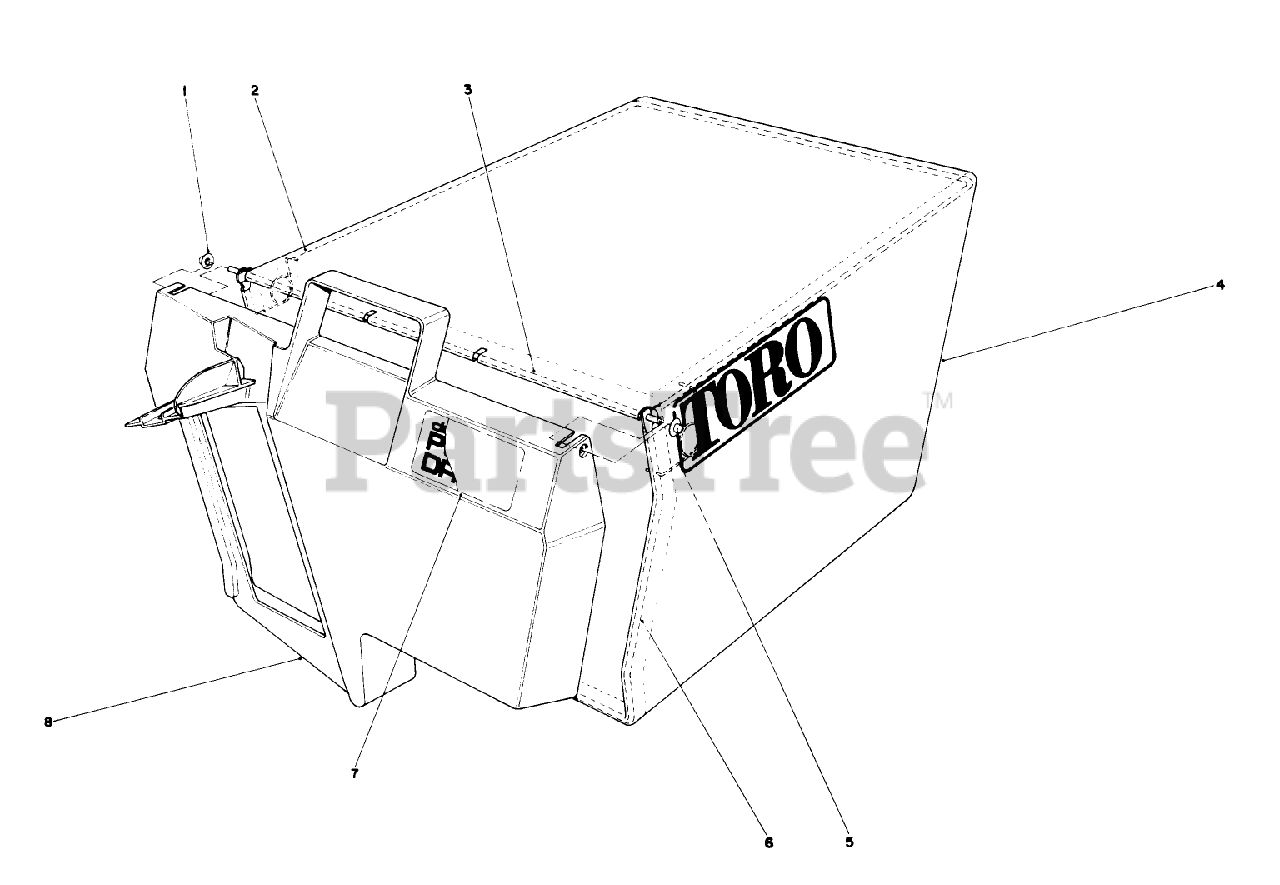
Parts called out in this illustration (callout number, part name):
1	NUT-PUSH
3	HINGE-DOOR, BAG
5	SPRING
6	FRAME-BAG
7	BAG DOOR DECAL
8	DOOR-BAG
